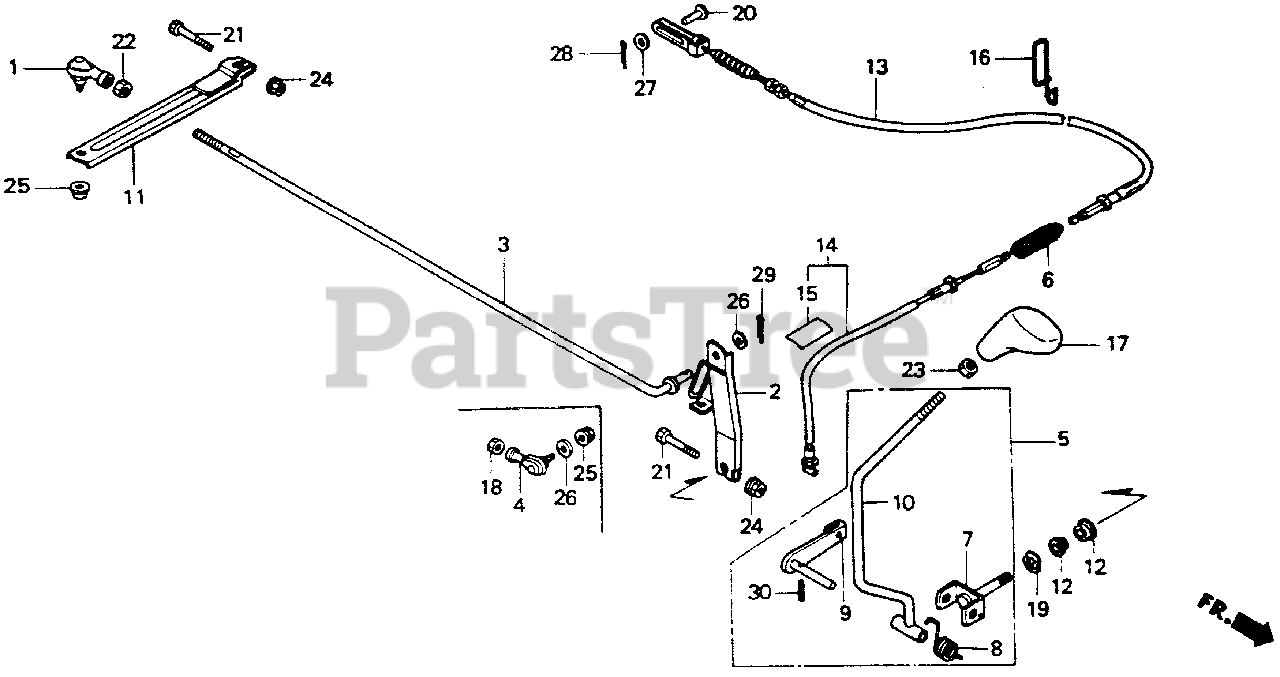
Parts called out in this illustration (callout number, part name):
1	JOINT, R. BALL
2	ARM, CHANGE (NOT AVAILABLE)
3	ROD, GEARSHIFT
4	JOINT, L. BALL
5	SHAFT, CHANGE LEVER
6	SPRING, CLUTCH DAMPER
7	SHAFT, CHANGE LEVER
8	SPRING, CHANGE LEVER
9	LINK, CLUTCH
10	LEVER, CHANGE (NOT AVAILABLE)
11	ARM, TRANSMISSION CHANGE
12	BUSH (15X19X18)
13	CABLE C, CLUTCH (CHANGE)
14	CABLE D, CLUTCH (CHANGE)
15	TAPE, PROTECTOR
16	GUIDE, CLUTCH CABLE
17	KNOB, SHIFT LEVER *NH105* (MAT BLACK)
18	NUT, HEX. (8MM)
19	WASHER, WAVE (15MM)
20	PIN, CLUTCH JOINT
21	BOLT, HEX. (6X32)
22	NUT, HEX. (8MM)
23	NUT, HEX. (12MM)
24	NUT, FLANGE (6MM)
25	NUT, FLANGE (8MM)
26	WASHER, PLAIN (8MM)
27	WASHER, PLAIN (6MM)
28	PIN, SPLIT (1.6X12)
30	PIN, SPRING (5X25)
